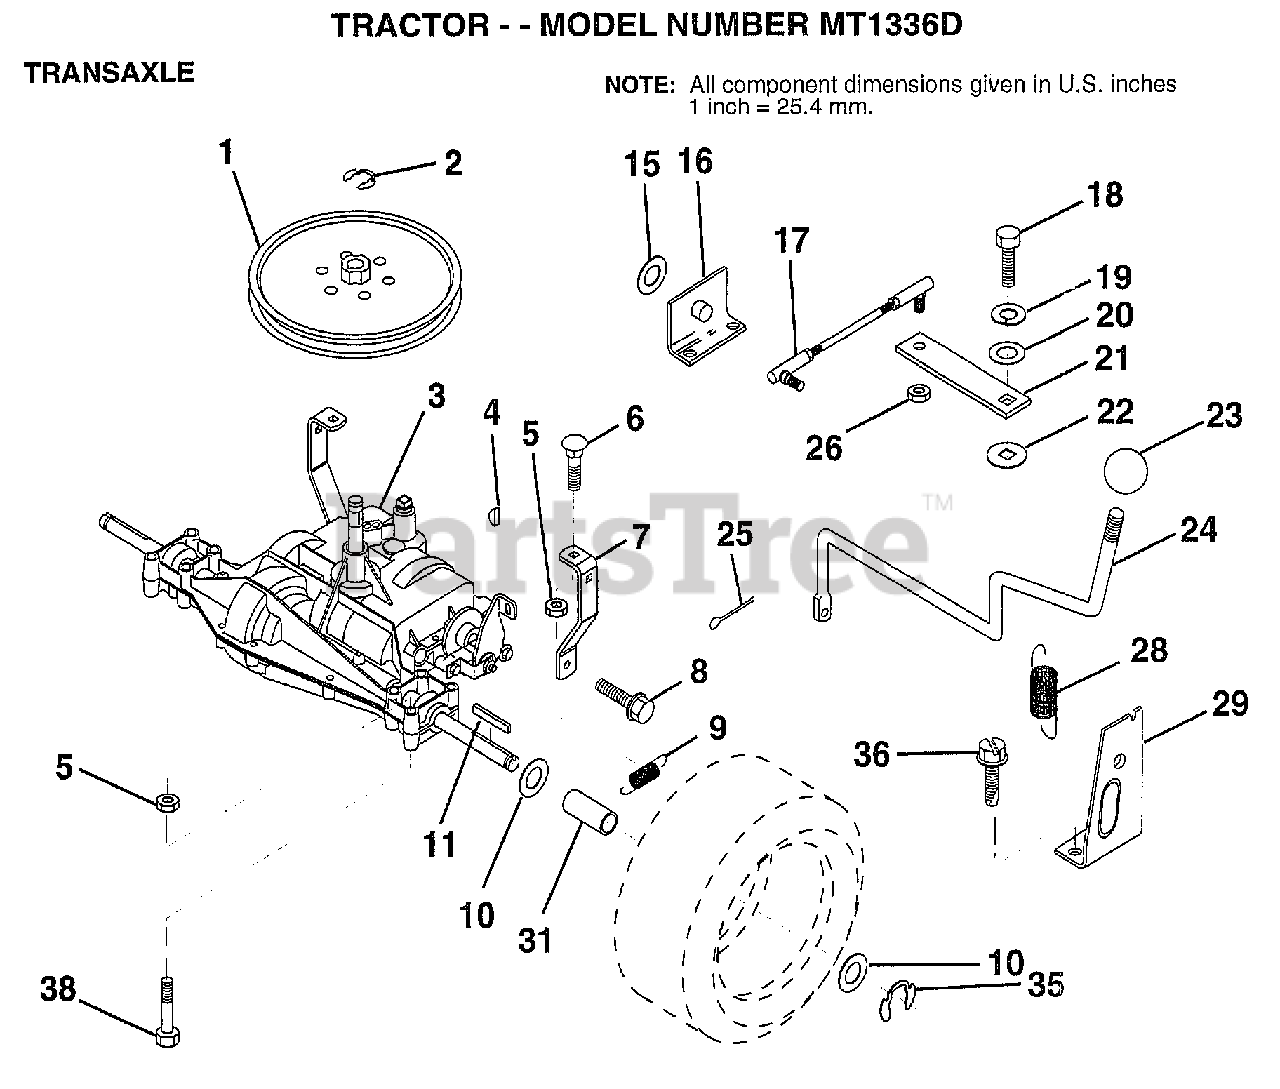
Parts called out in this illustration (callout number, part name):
1	PULLEY
6	BOLT
7	"STRAP,TORQUE"
8	SCREW
9	SPRING.BRAKE.RETU
10	WASHER
11	SQUARE KEY
16	"SUPT,HDLE SHT LH"
17	LINK SHIFT
18	BOLT.1/4-28.W/PAT
19	LOCKWASHER
20	WASHER LT
22	WASH-SHFT PLT LT
23	KNOB.DUCKHEAD.1/2
24	"ROD,SHIFT"
25	PIN COTTER 1/8
26	NUT.LOCK.5/16-24
28	"SPRING,EXT"
29	"SUPT,HDLE RH"
31	SPACER AXLE
35	E-RING LT
36	SCREW
38	BOLT.HX.FLG.5/16
